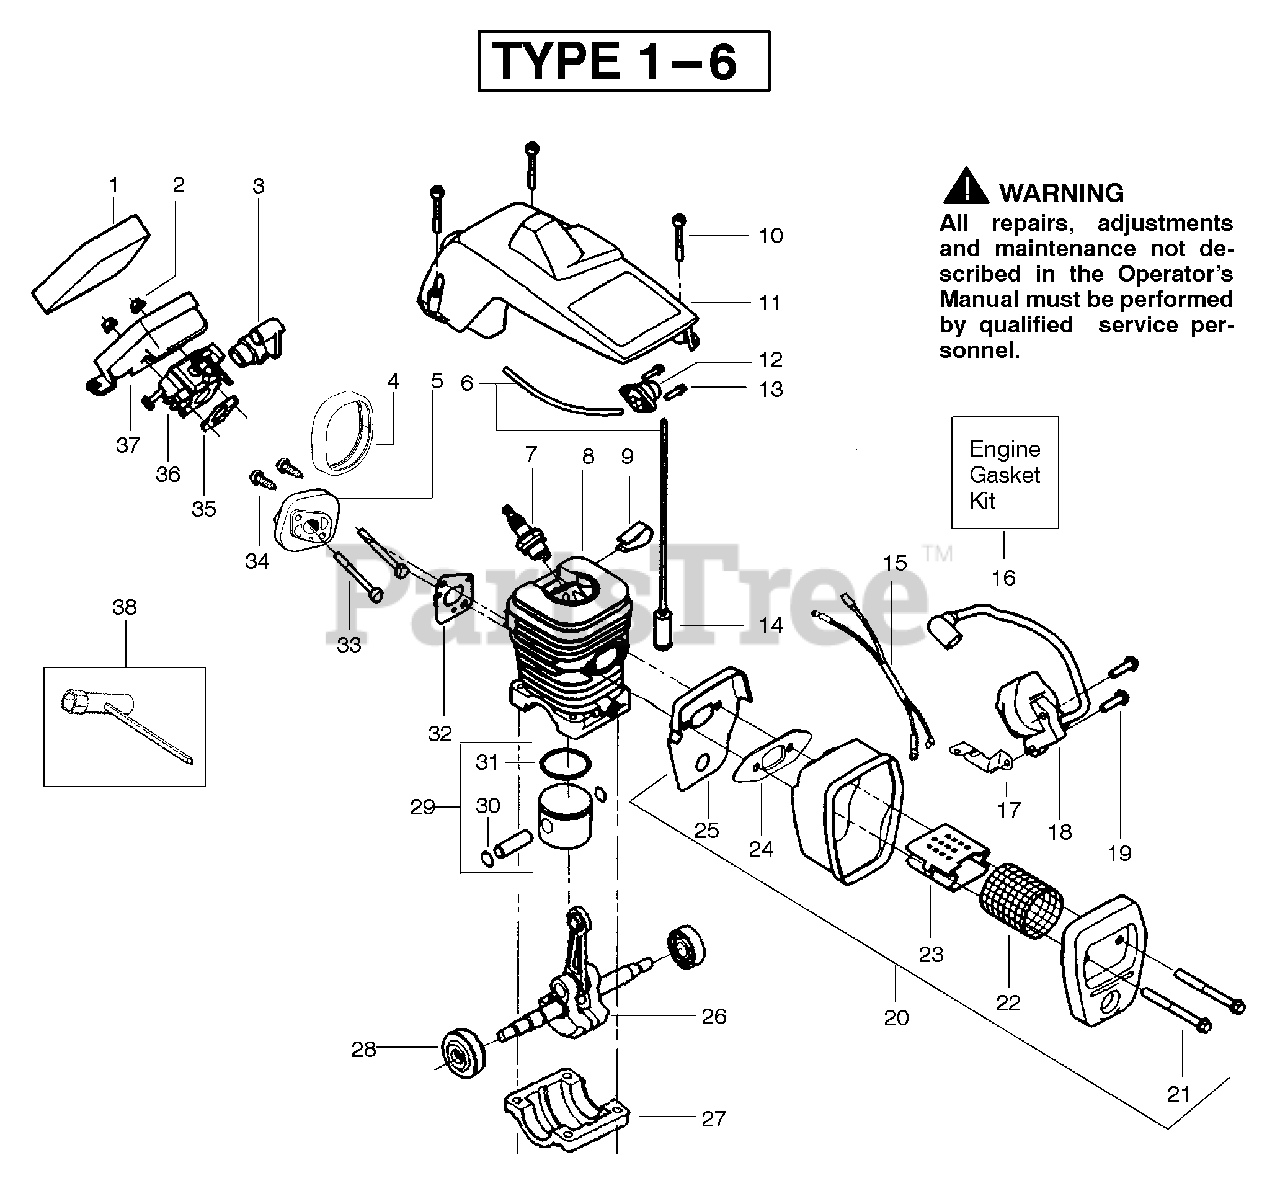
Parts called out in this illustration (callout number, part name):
1	Foam-Air Filter
3	Grommet-Carb Adjust
4	Seal-Carb Adapter
5	Adapter-Carb.
6	Kit-Fuel Line (Small)
7	Spark Plug (RCJ-7Y)
8	Cylinder
9	Clip-High Tension Lead
11	Shield-Cylinder
12	Assy-Air Purge
14	Assy-Fuel Pick-up
15	Assy.-Wire Harness
16	Kit-Engine Gasket
17	Strap-Ground
18	Module-Ignition
20	Assy-Muffler
22	Screen-Spark
23	Diffuser-Muffler
24	Gasket-Muffler(kit)
25	Backplate-Muffler
26	Assy.- Crankshaft
27	Cap-Crankcase
28	Assy.-Seal & Bearing
29	Kit-Piston
30	Retainer-Piston Pin
31	Ring- Piston
32	Gasket- Adapter(kit)
35	Gasket- Carb.(kit)
36	Kit-Carburetor
37	Housing-Air Filter
38	Wrench- Bar
